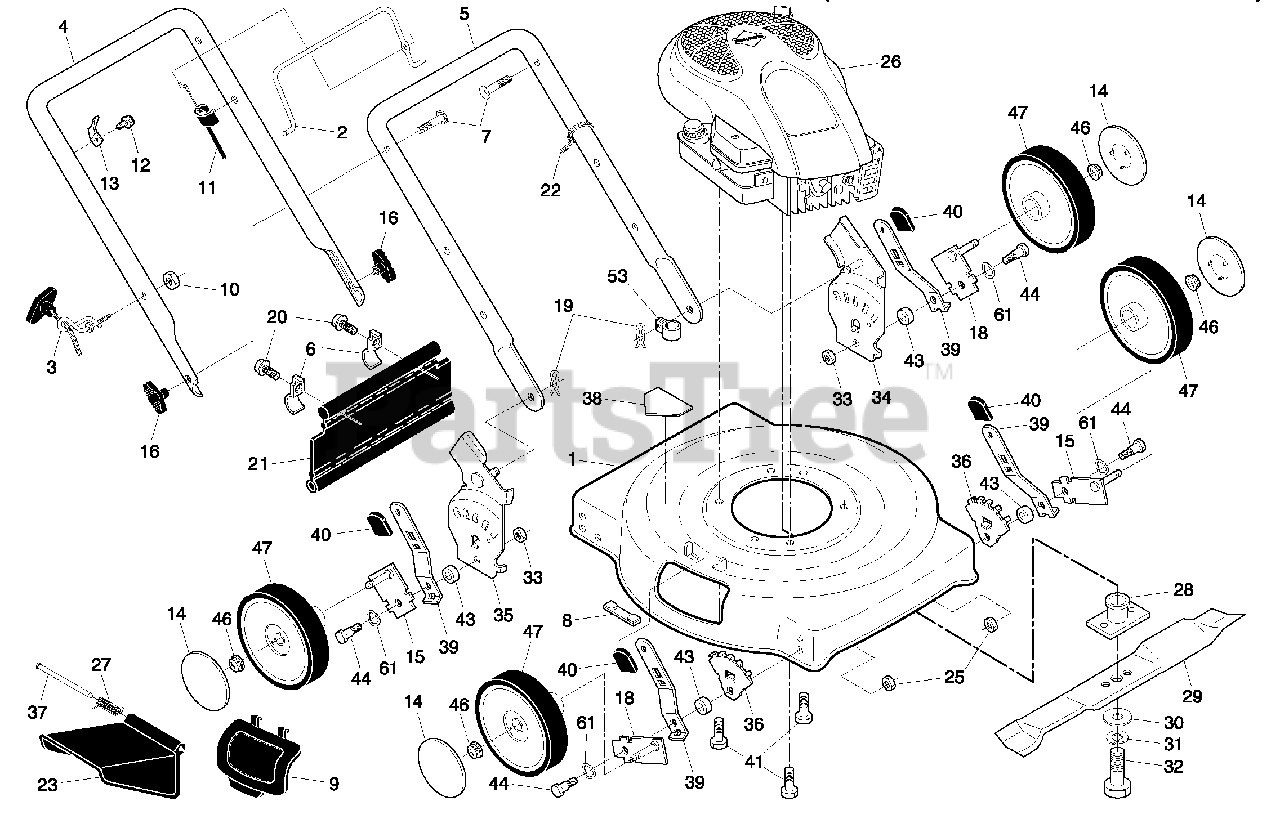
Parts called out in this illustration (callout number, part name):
1	Lawn Mower Housing Assembly
2	Control Bar
3	Rope Guide
4	Upper Handle
5	Lower Handle
6	Hinge Bracket
7	Handle Bolt 5/16-18
8	Clip, Closeout
9	Mulcher Plate
10	Locknut, Hex 1/4-20
11	Engine Zone Control Cable
12	Screw, Hex Head, Threaded, Rolled #10-24 x1/2
13	Up-Stop Bracket
14	Hubcap
15	Axle Arm Assembly (Rear, RH / Front, LH)
16	Handle Knob
18	Axle Arm Assembly (Rear, LH / Front, RH)
19	Hairpin Cotter
20	Screw
21	Rear Deflector
22	Wire Tie
23	Discharge Guard
25	Nut, Hex
27	Torsion Spring
28	Blade Adapter
29	22" Blade
30	Hardened Washer
31	Helical Lockwasher 3/8
32	Hex Head Screw 3/8-24 x 1/4 Grade 8
33	Nut, Hex, Centerlock 5/16-18
34	Support, Wheel Bracket, LH
35	Support, Wheel Bracket, RH
36	Adjuster, Wheel Bracket
37	Hinge Rod
38	Danger Decal
39	Selector Spring
40	Selector Knob
41	Screw, Hex Head, Threaded, Rolled 3/8-16 x 1
43	Spacer
44	Shoulder Bolt
46	Locknut, Hex 3/8-16
47	Wheel & Tire Assembly
53	Clip, Cable
61	Washer, Curved, Cylindrical
61	Operator's Manual, English
61	Operator's manual, French
61	Repair Parts Manual
